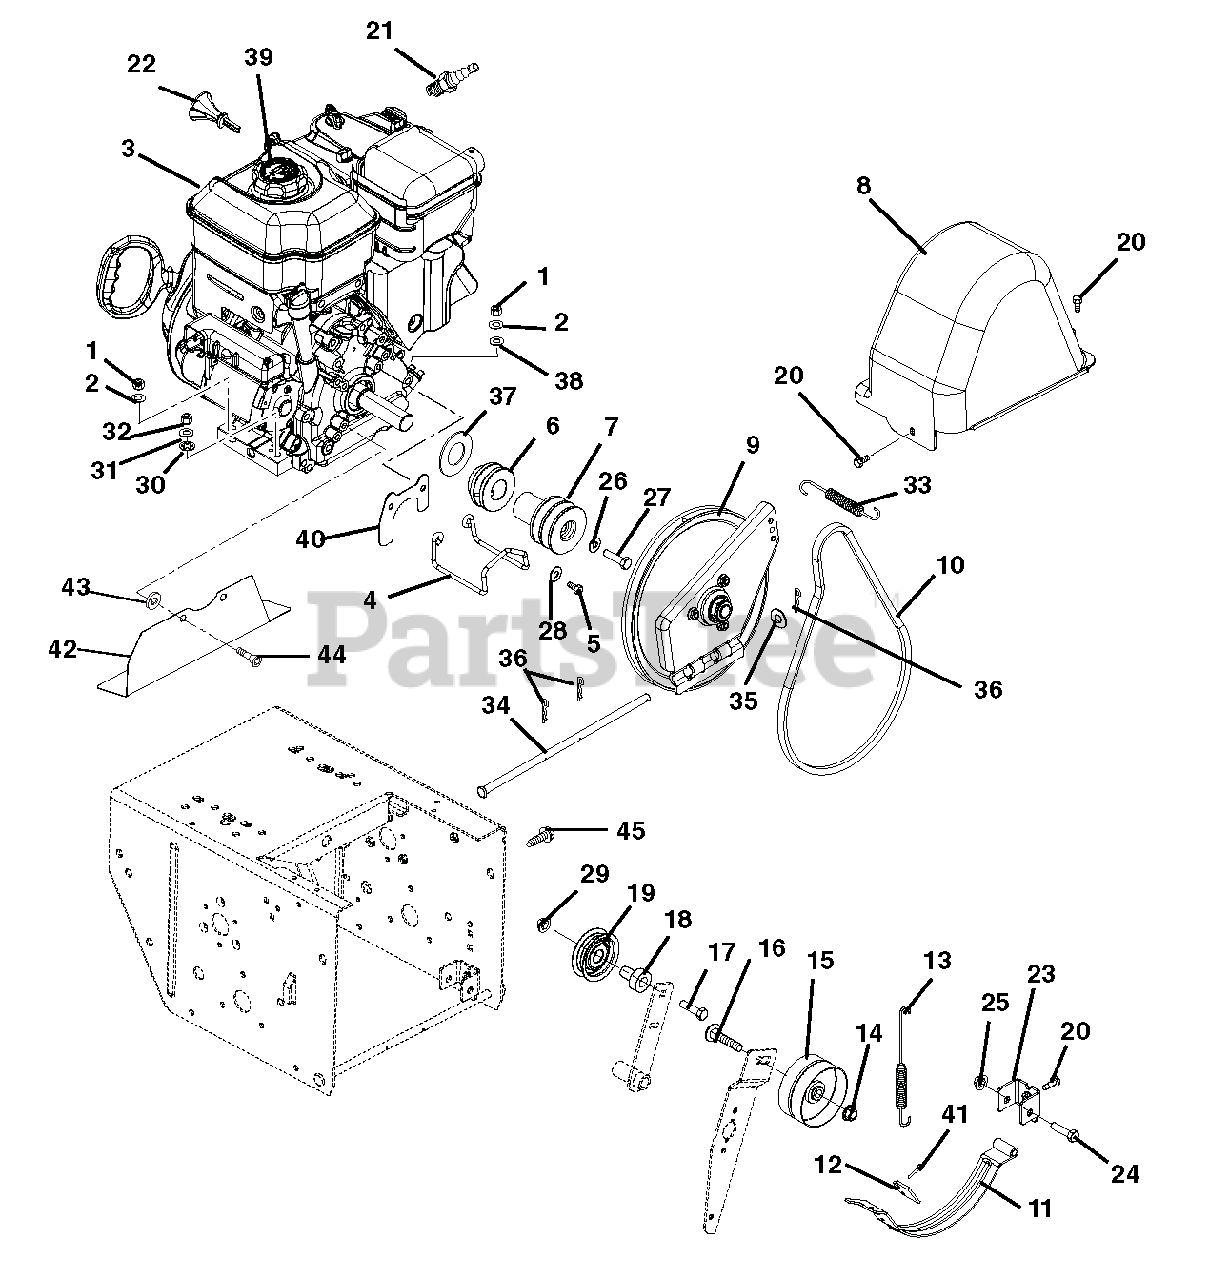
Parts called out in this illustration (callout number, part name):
1	@NUT-HEX .31-18 YWZC
2	WSHR-LK .312X.097 HVY YWZC
3	ENGINE,9.5HP 120V PWRBILT SNOW
4	FINGER, BELT
5	BLT-HEX .31-24X.75 YWZC GR5
6	SHEAVE, DRIVE
7	SHEAVE, ATTACHMENT 2-GRV
8	COVER, BELT
9	PLATE, SWING ASSEMBLY-DEEP
10	V-BELT, 3L-WRAPPED
11	ARM, BRAKE-ATTACHMENT
12	PAD, BRAKE
13	SG-TENS .056X.60X4.40
14	@NUT-LK-TOP-FLG .38-16 YWZC
15	IDLER-FLAT 2.75X.38 PAINTED
16	@BLT-RHDSSQNK .38-16X1.75 G5YZ
17	@BLT-HEX .31-18X1.25 GR5 YWZC
18	SPCR, BRG .315X.50X.688X.281
19	IDLER
20	SCR-TAP .25-20X.50 HWH TR YWZ
21	PLUG, SPARK
22	KEY, IGNITION PUSH/PULL B&S
23	PIVOT, BRAKE
24	@BLT-HEX .31-18X2.00 GR5 YWZC
25	@NUT-LK-TOP-FLG .31-18 YWZC
26	@WSHR-LK .38X.094 REG YWZC
27	BLT-HEX .38-24X2.25 YWZC GR5
28	WSHR-LK .312X.097 HVY YWZC
29	@NUT-LK-TOP-FLG .31-18 YWZC
30	WSHR-LOCK INT .31 YWZC
31	@WSHR-FL-STL.344X.688X.065YWZC
32	@NUT-LK-CTR .31-18 YWZC
33	SG-TENS .048X.50X2.8
34	PIN, PIVOT
35	@WSHR-FL-STL.406X.812X.065 YWZ
36	PIN-HAIR, ENDRIES #25 YWZC
37	WSHR-FL-STL- 1.062X2.0X.134 YZ
38	@WSHR-FL-STL.38X.875X.083 YWZC
39	CAP, FUEL - BRIGGS
40	GUARD, BELT COVER - BRIGGS
41	RVT-POP .187 YZ
42	BAFFLE, ENGINE
43	WSHR-FL-STL .536X1.07X.109 YZ
44	SCR-MCH.31-24X.75FLCTRSK EP80
45	@SCR-TAP .25-20X1.50 HWH TR YZ
